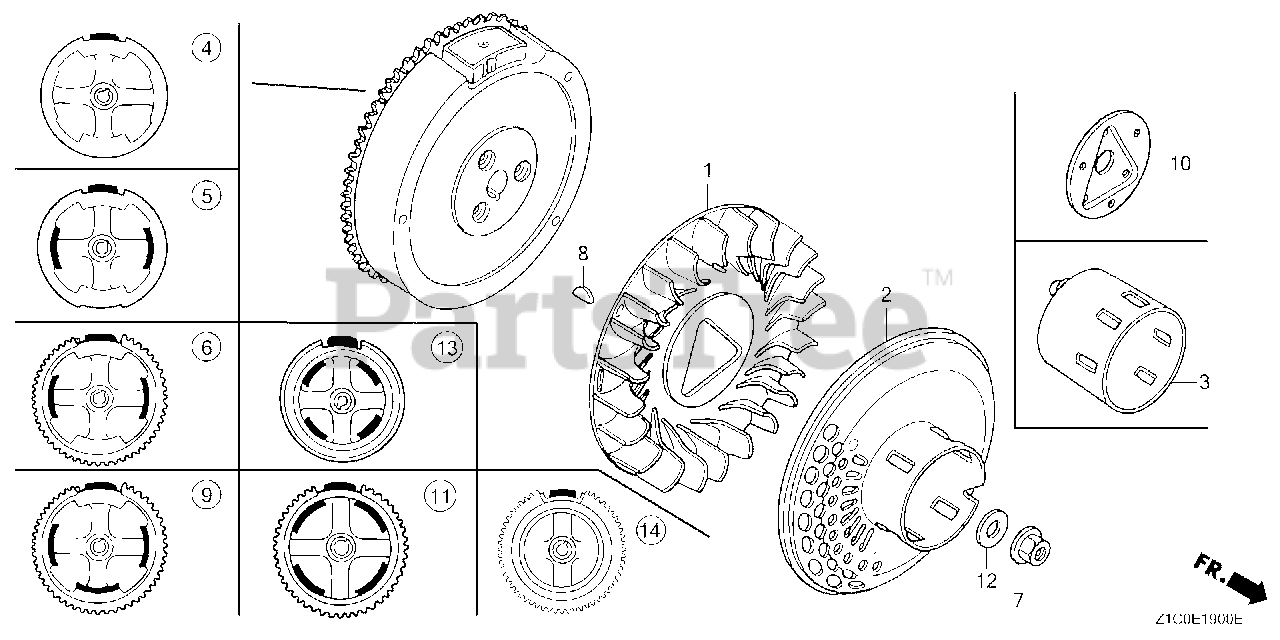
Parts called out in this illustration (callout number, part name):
1	FAN, COOLING
3	PULLEY, STARTER
4	FLYWHEEL
7	NUT, SPECIAL (16MM) (1)
8	KEY, SPECIAL WOODRUFF (25X18)
